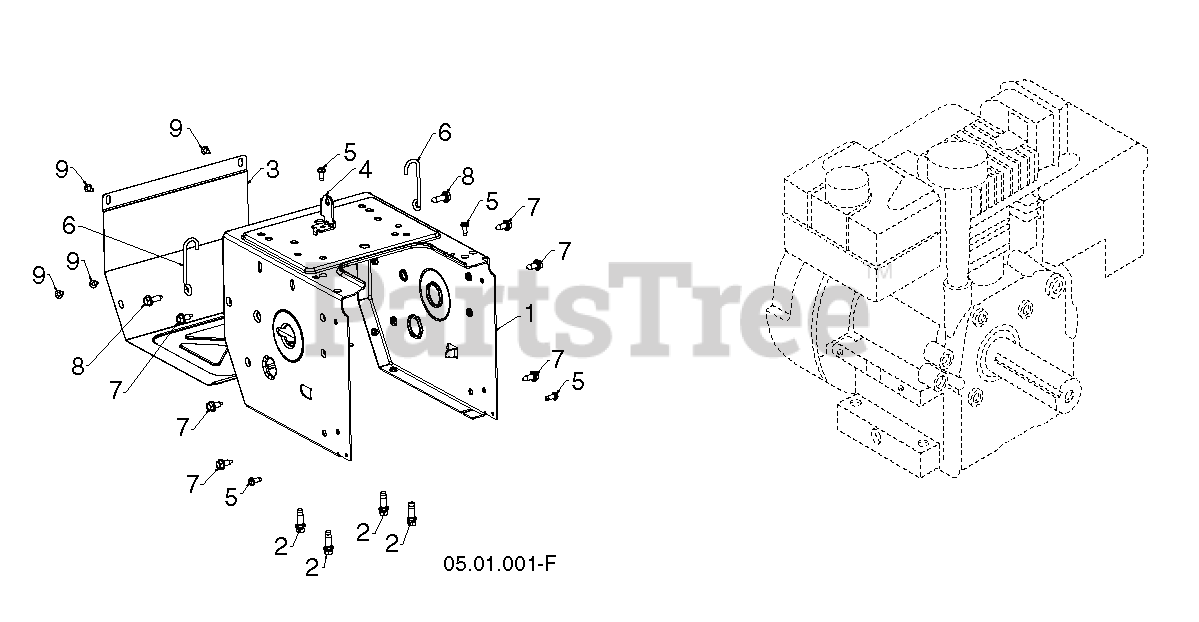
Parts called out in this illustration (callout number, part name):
1	FRAME.GEAR.CASE.SNOW.BLACK
2	BOLT 3/8-16X1-1/8
3	Snow Frame Cover, Black
4	BRACKET.SHIFTER.BZP
5	SCREW 14-20 X 5/8
6	RP.SUPPORT CABLES WIREFORM
7	BOLT.HEX.HD.WASHER.5/16-18X.75
8	Hex Washer Head Bolt, 5/16-18 X 3/4 Thread Forming
